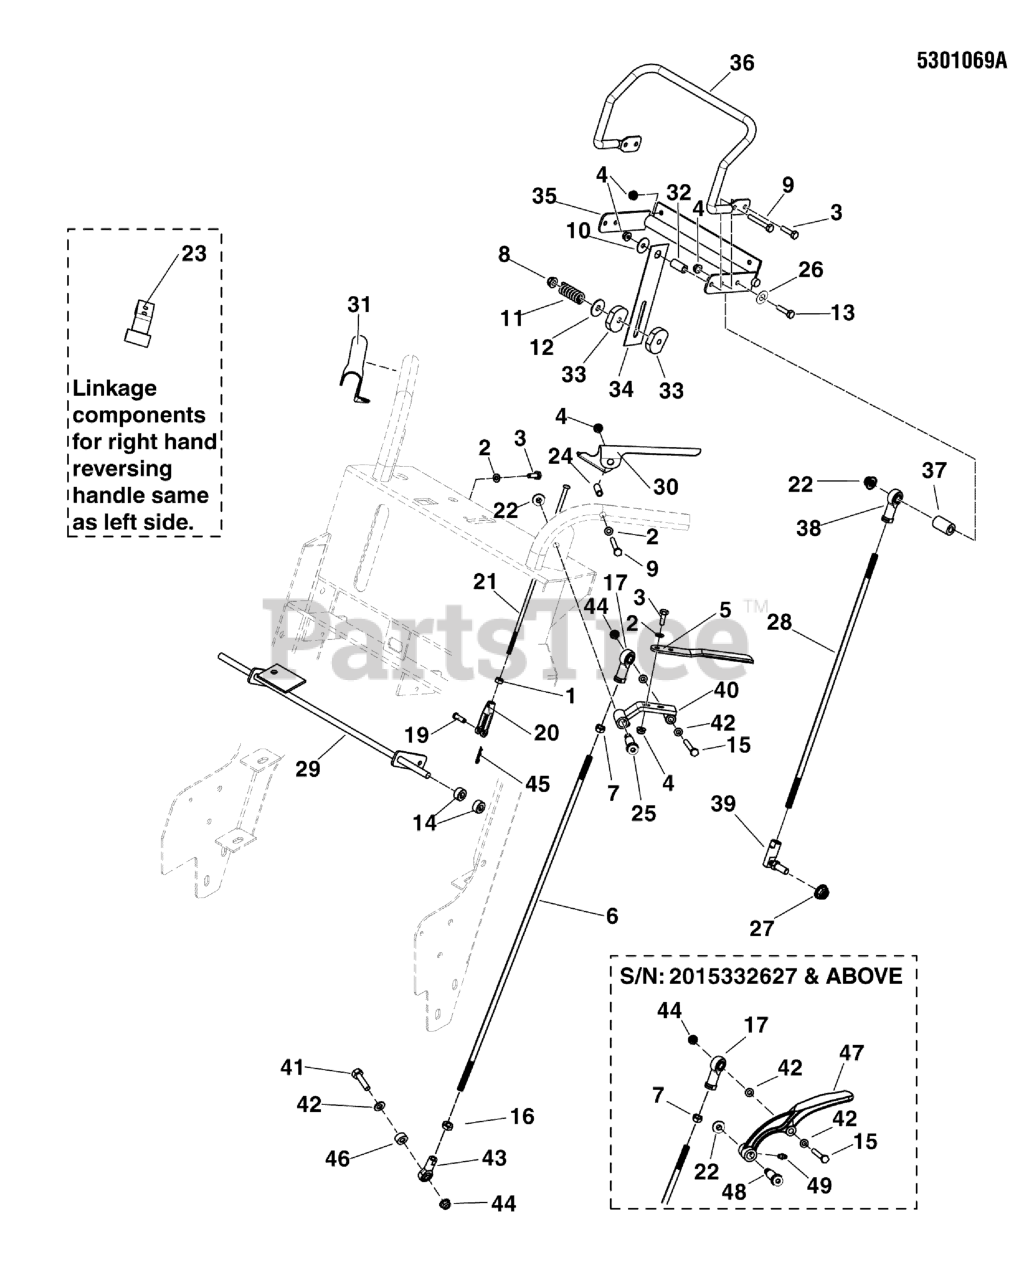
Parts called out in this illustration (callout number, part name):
1	HN, 1/4F GR5 YZ
2	WASHER, 1/4 SAE
3	BOLT, 1/4-20 X 3/4 GD5 YZ
4	NUT, 1/4-20 HEX NYLOCK FLANGE
6	ROD, 5/16-24 X 33.2 LH-RH, YZ
7	NUT, 5/16-24 HEX, LH
8	NUT, 5/16-18 HEX NYLOCK FLANGE
9	BOLT, 1/4-20 X 1-3/4" GD5 YZ
10	WASHER, 1/4" FENDER
11	SPRING-COMP, .428IDX2.50LGX.154WR, BZ
12	WASHER, 5/16" FENDER
13	BOLT, 3/8-16 X 2-1/2" GD5 CZ
14	COLLAR, 3/8" SET
15	BOLT, 5/16-18 X 2-1/2 GD5 YZ
16	NUT, 5/16-24 HEX
17	BALL JOINT 5/16-24 LH FEMALE STAMPED STL
18	COLLAR, 5/16" SET
19	PIN, CLEVIS, 1/4 X 7/8, PLATED
21	ROD, OPC LINK, SNP PRO WB
22	NUT, 3/8-16 HEX NYLOCK FLANGE
23	WELD, REVERSE HANDLE - RH
24	SPACER, .26 X .38 X 1.250, YZ
25	BOLT, 3/8-16 X 1, 1/2 SHOULDER
26	WASHER, 3/8 SAE
27	NUT, 3/8-24 HEX NYLON LOCK
28	ROD, CRUISE CONTROL, SNP PRO WB
29	WELD, OPC SHAFT- RED
32	SPACER, .26 X .50 X 1.00 YZ
33	SPACER, .34 X 1.54 X .25 UHMW
34	PLATE, FRICTION CONTROL
35	WELD, SPEED CONTROL,DDS - RED
36	BAR, SPEED CONTROL, DIPPED
37	SPACER, .38 X .75 X 1.25, YZ
38	ROD END, 3/8-24 LH FEMALE
39	BALL JOINT, 3/8-24 FEM, STUD.
40	WELD, REVERSE HANDLE - LH
41	BOLT, 5/16-18 X 1-1/4 GD5 TFL, CZ
42	WASHER, 5/16" SAE
43	BALL JOINT 5/16-24 RH FEMALE STAMPED STL
44	NUT, 5/16-18 HEX NYLOCK FLANGE
45	PIN, HAIR, .0585 X 1-1/8, 1/4 EYE, YZ
46	SPACER, .33 X .50 X .25, CZ
47	HANDLE, REVERSING - BLK
48	BOLT, 3/8-16 X 1, 1/2 SHOULDER
49	GREASE FITTING, 1/4-28 STRAIGHT
